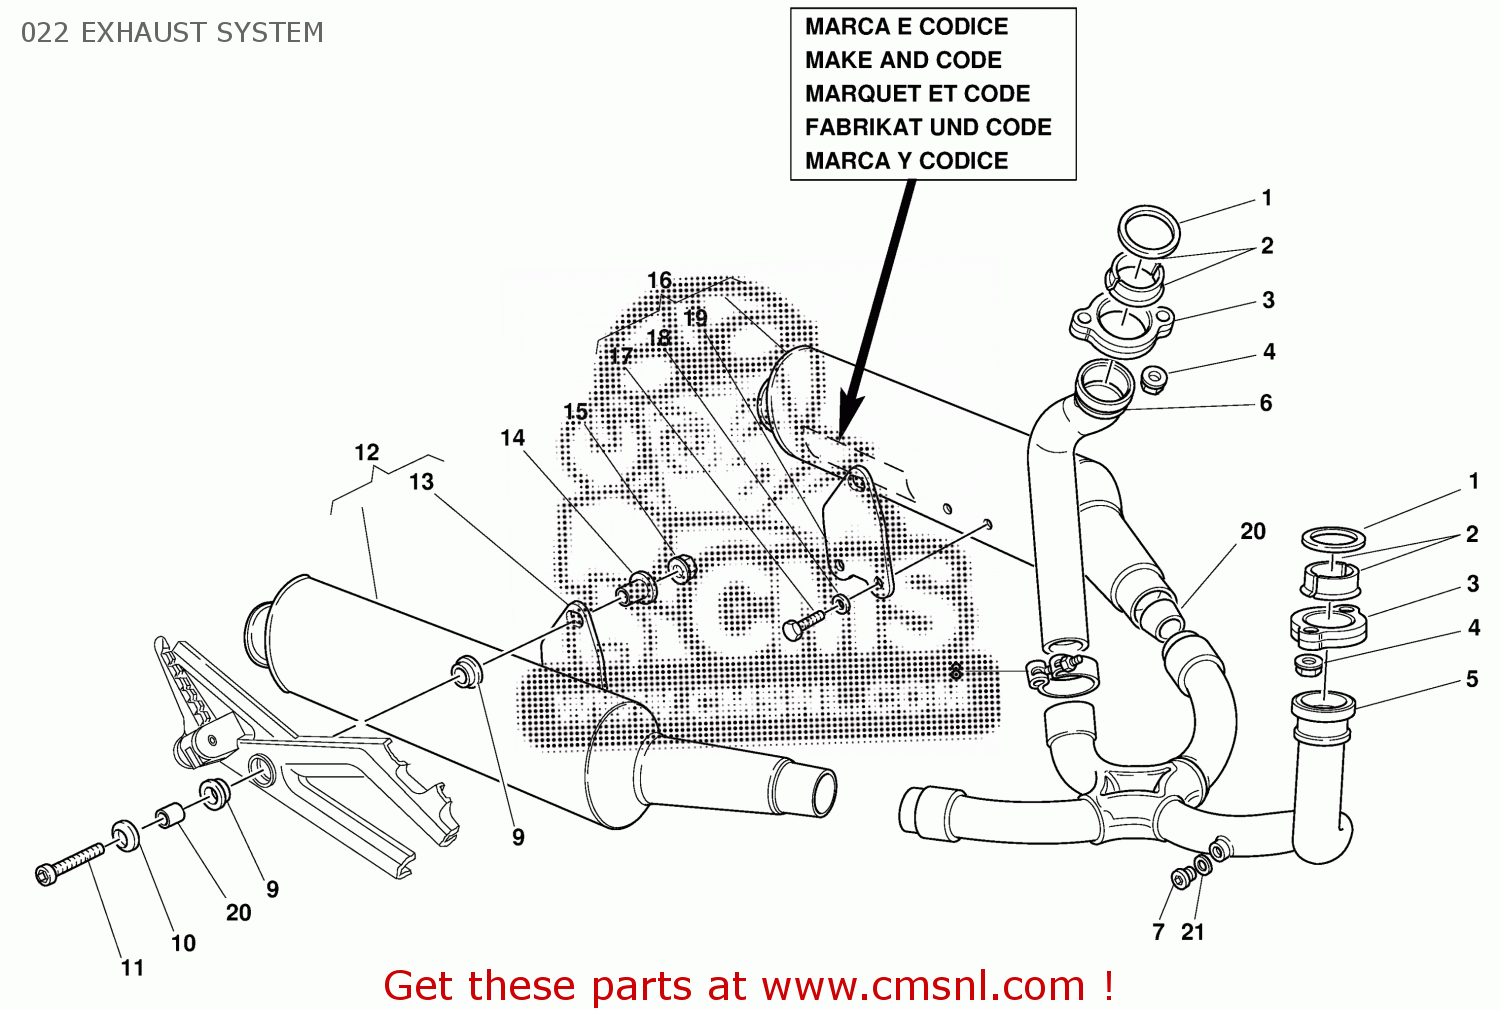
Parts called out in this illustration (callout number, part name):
1	GASKET, EXHAUST PIPE
2	HALF BUSH
3	RING NUT
4	NUT
5	HORIZONTAL EXHAUST PIPE
6	VERTICAL EXHAUST PIPE
7	PLUG ASSY
8	CLAMP
9	DAMPER
10	WASHER 6.4X25X1.5
11	SCREW M6X35
12	RIGHT SILENCER
13	BRACKET, RIGHT SILENCER
14	SPACER
15	NUT, FLANGED M6X1.00
16	LEFT SILENCER
17	SCREW
18	WASHER
19	BRACKET, LEFT SILENCER
20	BUSH
21	COPPER GASKET 11.9X8.2X2
